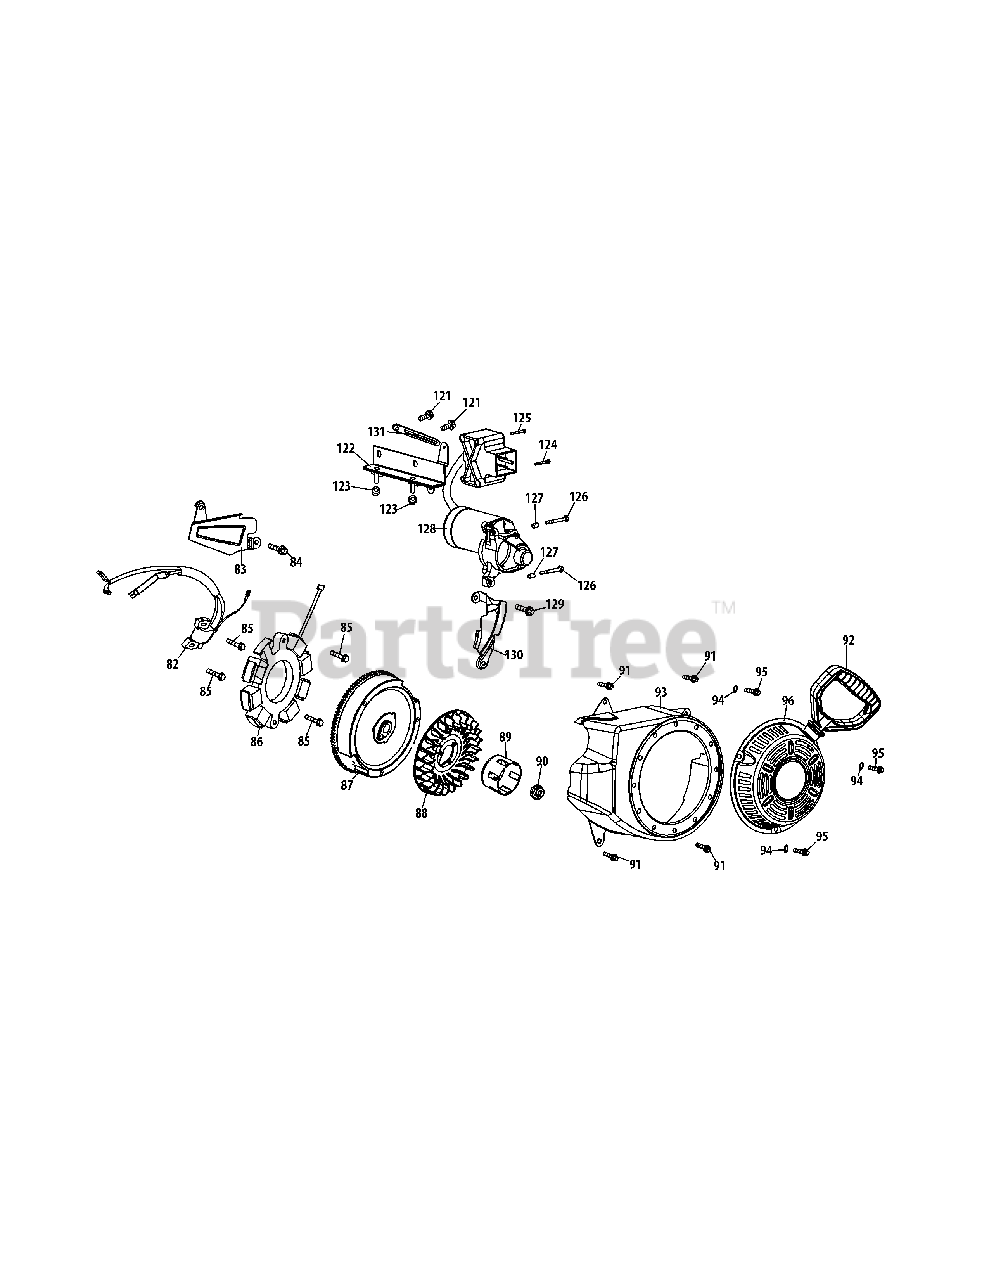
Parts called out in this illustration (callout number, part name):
82	Ignition Coil Assembly
83	Air Flow Shield
84	Bolt M6×10
85	Bolt M6×25
86	Coil Assy., Charge
88	Fan,Cooling
89	Pulley, Starter
90	Nut, Special,M14×1.5
91	Bolt M6×12
92	Recoil Starter Handle
93	Blower Housing
94	Gasket 6
95	Bolt M6×10
96	Recoil Starter
121	Bolt M6×10
122	Switch Housing Mounting Bracket
123	Nut, M6
124	Bolt M4×55
125	Bolt M4×60
126	Bolt M6×32
127	Dowel Pin 8×8
128	Electric Starter
129	Bolt M6×18
130	Blower Housing Shield
131	Flexible Clamp
